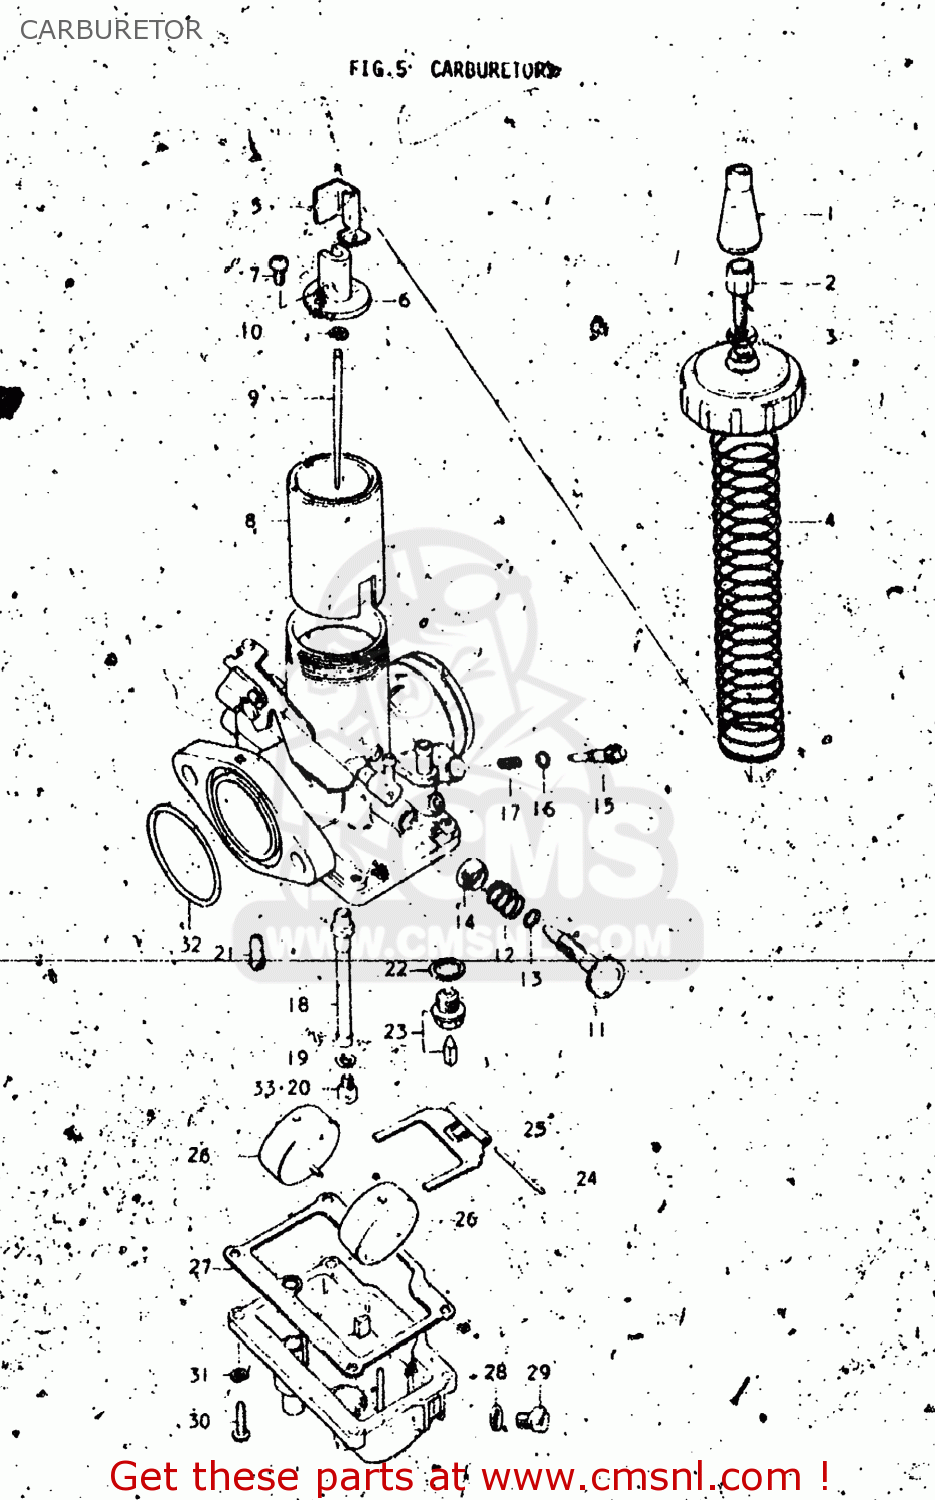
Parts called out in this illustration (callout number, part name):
1	CAP
2	ADJUSTER,CABLE
3	NUT
4	SPRING
5	CLIP
6	CONNECTOR
7	SCREW
9	NEEDLE JET
10	CLIP
11	ADJUSTER
12	SPRING,THROTTLE STOP
13	O-RING
14	COVER
15	SCREW,PILOT AIR
16	O RING
17	SPRING
18	JET,NEEDLE
19	WASHER
20	JET,MAIN(145)
21	JET
22	GASKET,VALVE SEAT (NAS)
23	VALVE ASSY,NEEDLE
24	PIN,FLOAT
25	ARM,FLOAT
26	FLOAT
27	GASKET,FLOAT CHAMBER (MCA)
28	GASKET,DRAIN,PLUG (NAS)
29	PLUG
30	SCREW
31	LOCK WASHER
32	O-RING
33	JET
